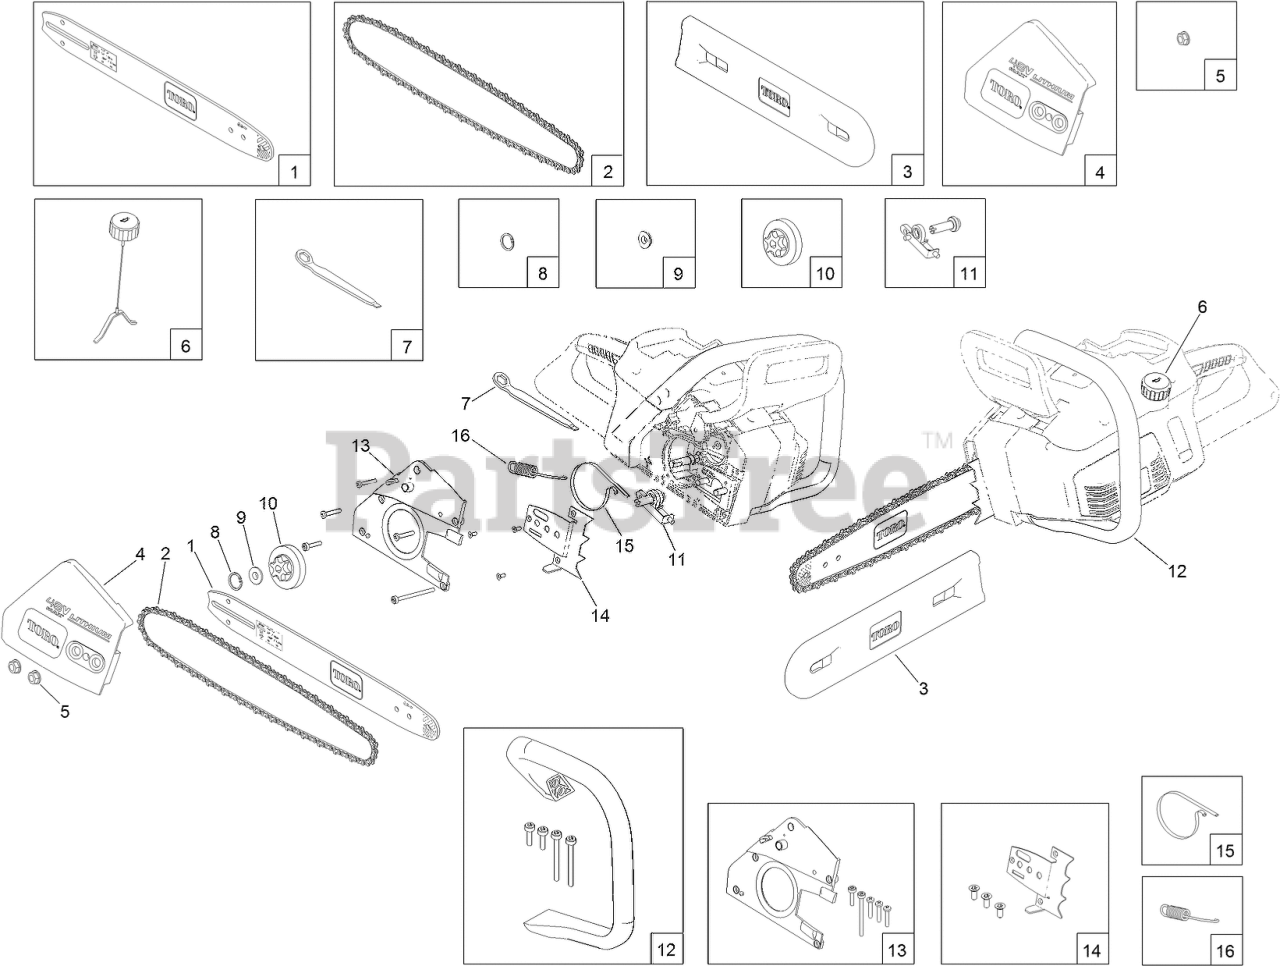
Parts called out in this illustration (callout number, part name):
1	BAR-REPLACEMENT
2	CHAIN-REPLACEMENT
3	SLEEVE-BAR
4	COVER-BAR/CHAIN
5	NUT-M8
6	OIL CAP ASM
7	WRENCH
8	SNAP-RING
9	SPACER
10	SPROCKET
11	BAR AND CHAIN ADJUSTER ASM
12	HANDLE ASM
13	INTERNAL COVER ASM
14	BUCKING TEETH BRACKET ASM
15	BRAKE-BAN
16	SPRING-LEVER, BRAKE
